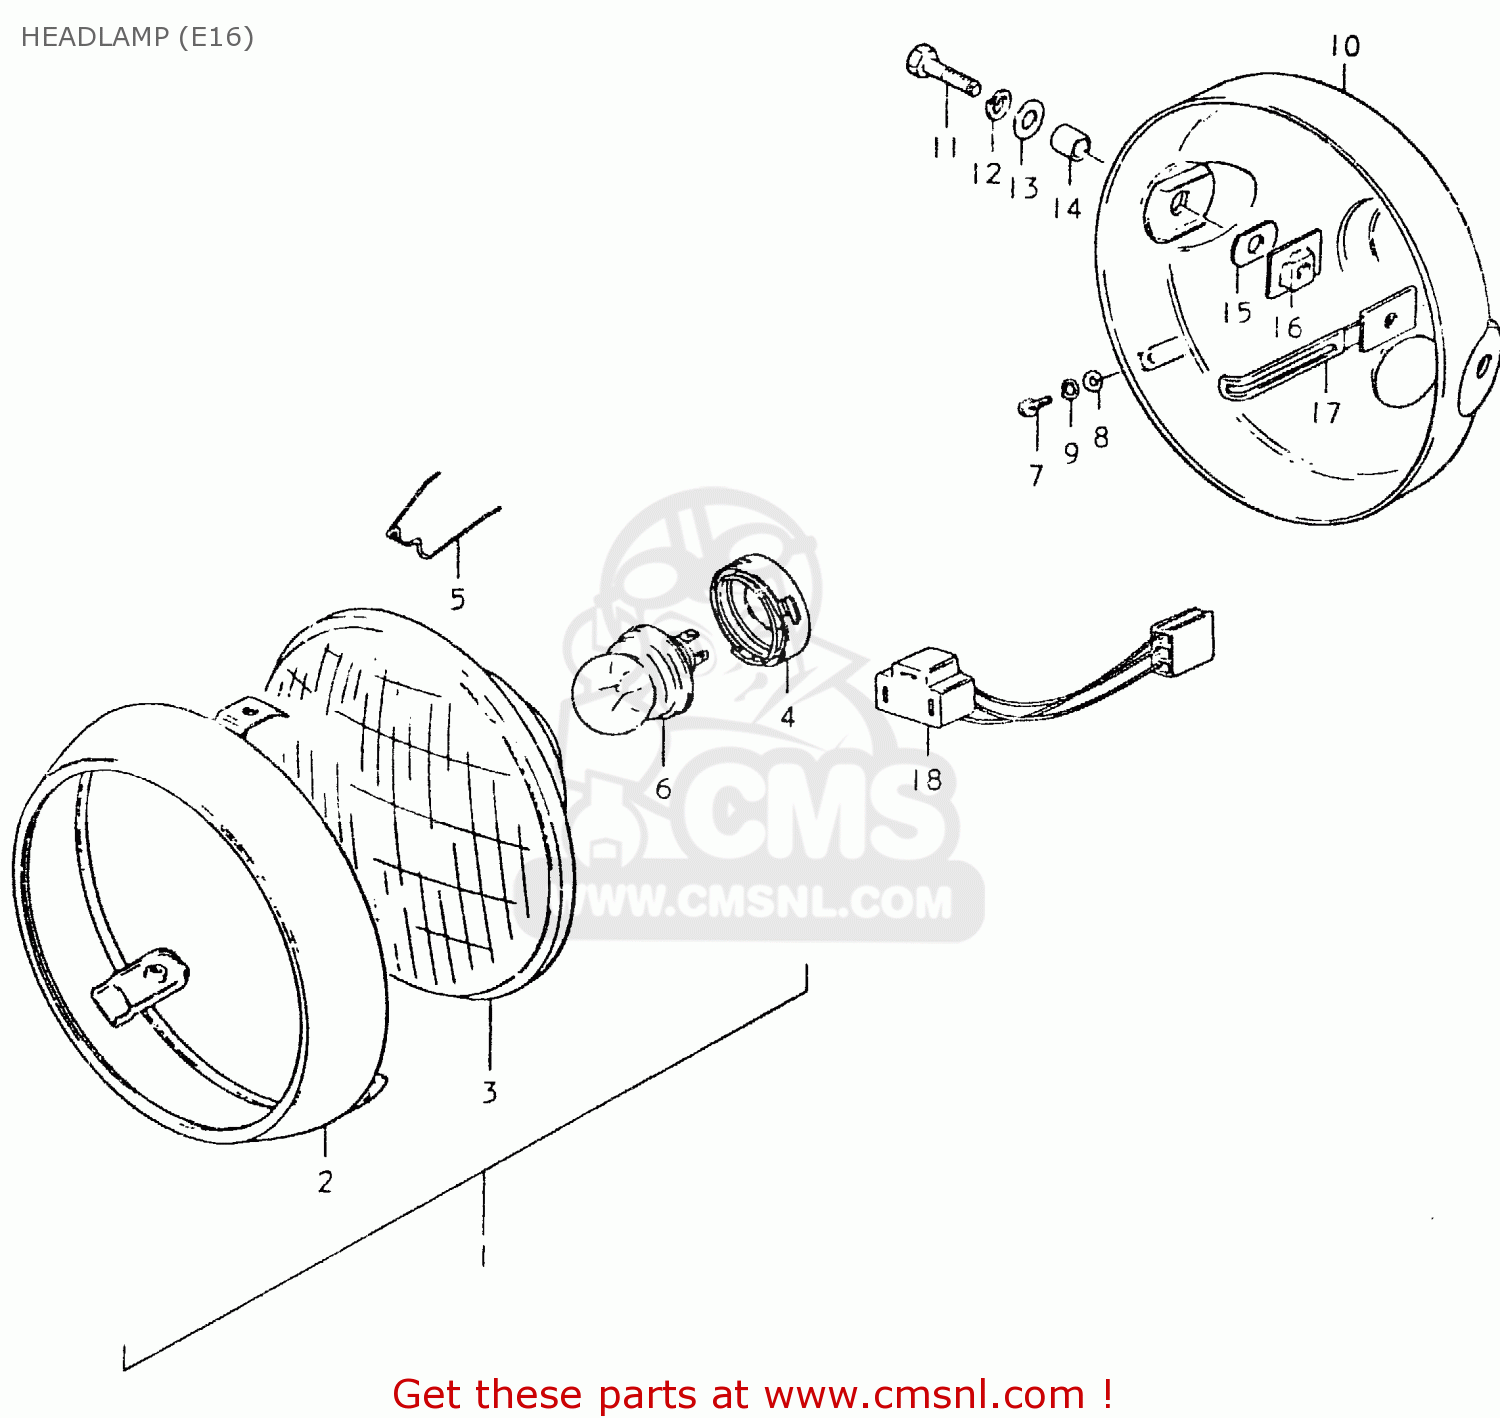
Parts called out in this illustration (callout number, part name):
1	HEADLAMP ASSY
2	RIM
3	UNIT
4	SETTER,BULB
5	SPRING
6	BULB (6V,45/40W)
7	SCREW
8	WASHER
9	LOCK WASHER
10	HOUSING,HEADLAMP
11	BOLT
12	LOCK WASHER
13	WASHER
14	SPACER (8.8X12X7)
15	CUSHION
16	PLATE,HEADLAMP HOUSING
17	PLATE,HEADLAMP HOUSING
18	LEAD WIRE,HEADLAMP
